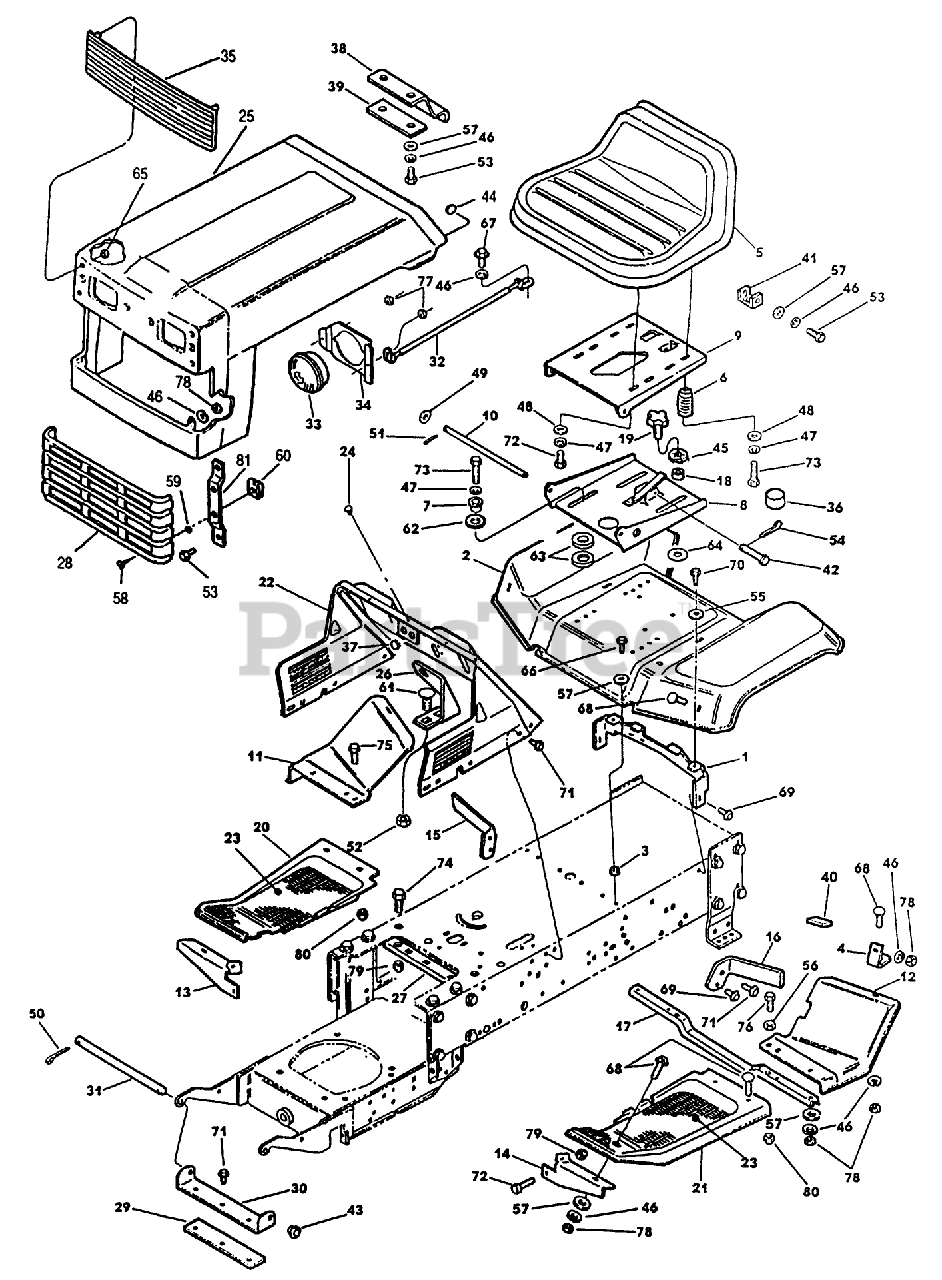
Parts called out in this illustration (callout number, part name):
1	BRACKET-SEAT SUPT
8	SEAT SUPPORT AY
9	PIVOT AY - SEAT *B
22	INST PANEL & DECAL *B
25	HOOD GRILLE WLDMT *G
28	INSERT - GRILLE
36	CAP-PROTECTOR
43	BEARING-NYLINER
53	SCREW-HH
58	FASTENER-1/4 TURN
63	WASHER-PLASTIC
70	SCREW-HWH
72	SCREW - HEX
80	NUT-LOCKING
